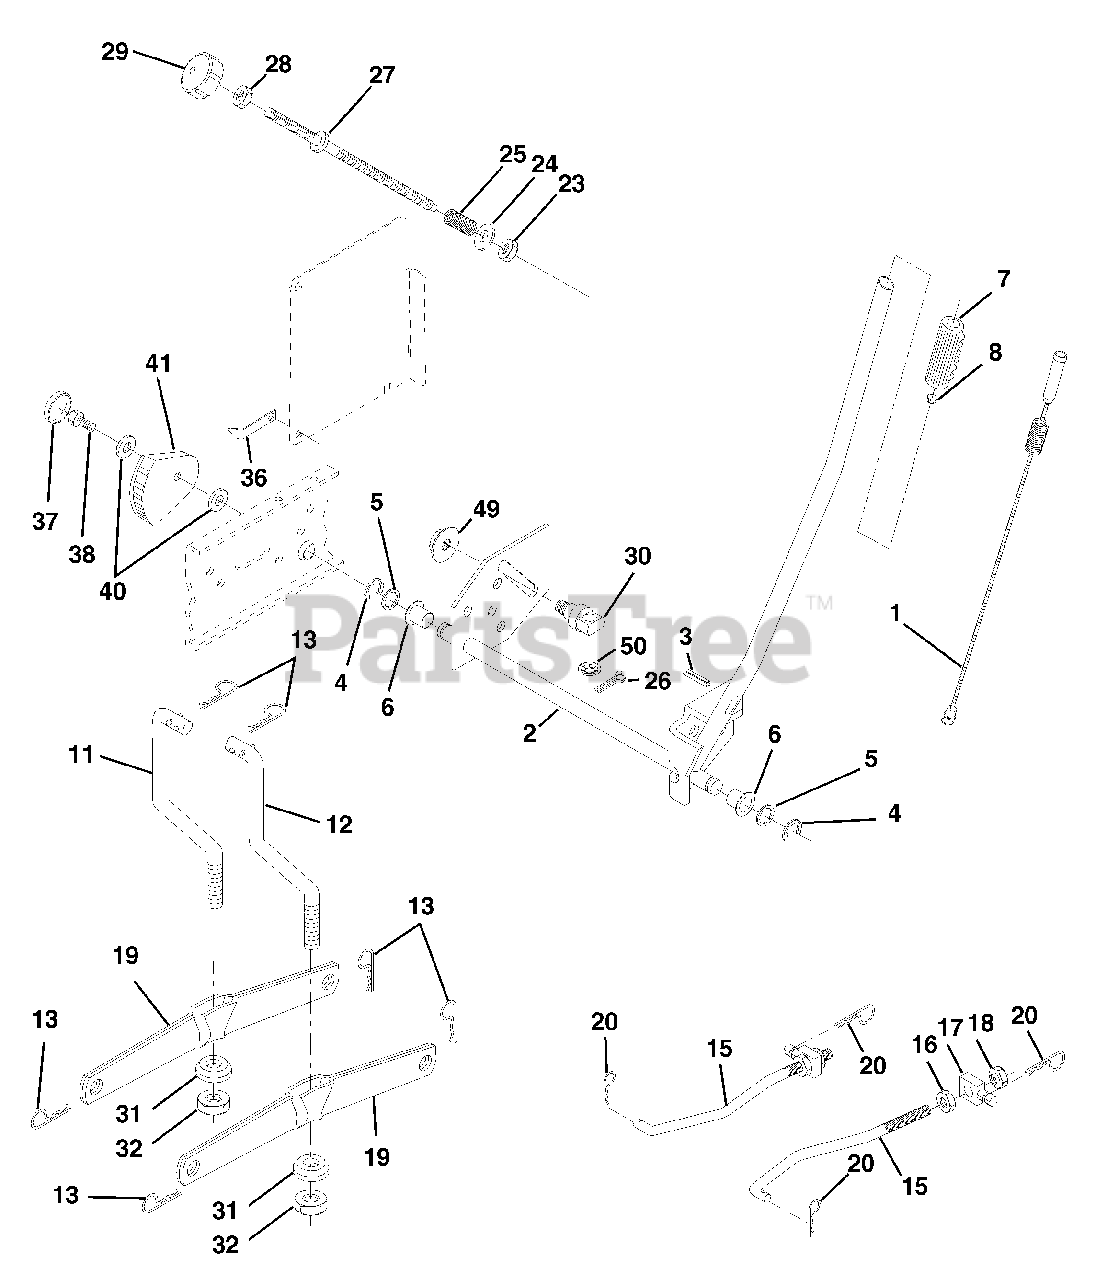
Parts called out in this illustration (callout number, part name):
1	Wire Asm Inner/Spring W/Plunger LT
2	Shaft Asm Lift RH w/Inf
3	Pin Groove 1 500 Zinc
4	E Ring #5133-62
5	Washer 21/32 X 1 X 21 Ga
6	Bearing Nylon Blk 629 Id
7	Grip Handle Fluted Blk
8	Button Plunger Black
11	Link Lift LH Fixed Length
12	Link Lift RH Fixed Length
13	Retainer Spring
15	Link Front
16	Nut Jam Hex 1/2-13 Unc
17	Trunnion Blk Zinc
18	Nut Crownlock 1/2-13unc
19	Arm Suspension Rear
20	Retainer Spring
23	Nut Special
24	Washer 13/32 X 5/8 X 16 Ga
25	Spring 2-1/8"
26	Pin Cotter 3/32 X 1/2
27	Rod Adj Lift Zinc 7.49 Wrk Lg
28	Nut Hex Jam 3/8-16 Unc
29	Knob Inf 3/8-16 Unc Blk W/sym
30	Trunnion Infin Height
31	Bearing Pvt Lift Spherical
32	Nut Crownlock 3/8 - 24
36	Indicator Height STLT
37	Plug Hole Blk 1.485/1.515 Dia.
38	Screw Thdrol 5/16-18 x 3/4
40	Washer 11/32 x 1-1/2 10 Ga.
41	Scale Ind. Height Blk.
49	Nut Hex Flange Lock
50	Nut, Push Phos & Oil
